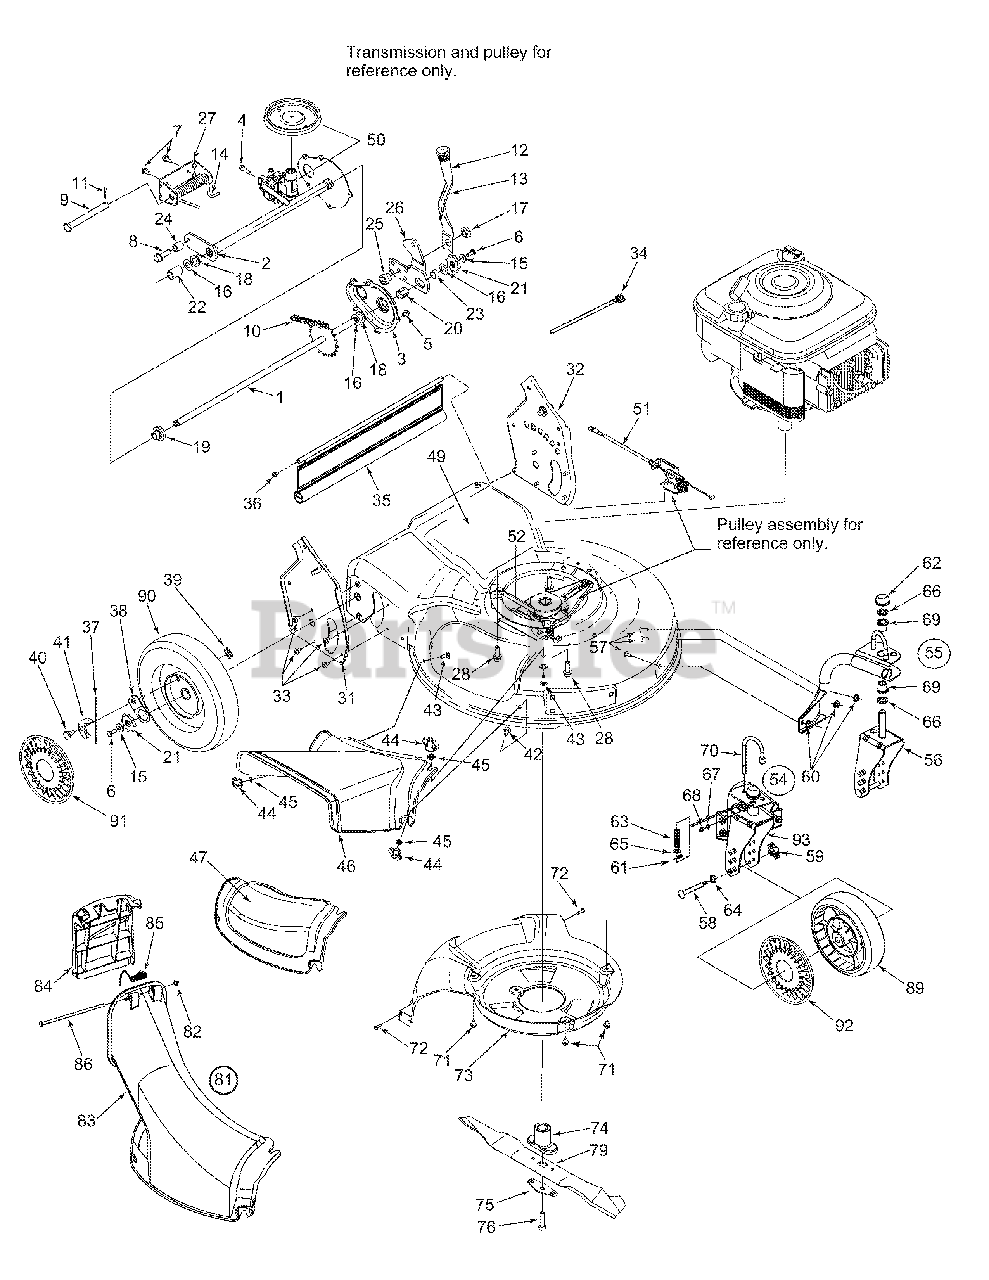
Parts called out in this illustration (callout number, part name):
1	Axle Ass’y 20T x 21.46" Lg.
2	Trans Axle Ass’y
3	Chain Cover Ass’y
4	Hex Wash HD Scr 5/16-18 x .62
5	Hex Wash HD Tapp Scr 1/4-20 x .38
6	Hex Bolt 1/4-20 x .62
7	Hex Wash Hd. Scr 1/4-20 x .625" Lg
8	TT Screw 3/8-16 x 1.25
9	Clevis Pin .5" Dia. x 4.62" Lg.
10	Chain, No. 48 End less .50 x 24 links
11	Cotter Pin
14	RH Torsion Spring
15	Cupped Wash. .25 ID x .88 OD x .062
16	Washer, Flat .505 ID x 1.0
17	Shoulder Nut .625 DIA. x .165
18	Flange Bear ing .506 ID
19	Hex Flange Bear ing
20	Hex Sleeve Bear ing .504 x .830 Lg.
21	Ratchet Wheel
22	Spacer .55 ID x .75
23	Sleeve .511 ID x .70 OD x .37" LG.
24	Spacer .38 x .625" Lg.
25	Shoulder Spacer .385 ID x .715" Lg.
27	Spring Bracket
28	Hex Wash HD Tap Scr 3/8-16 x .88
31	Handle Brkt. Ass’y RH
32	Handle Brkt. Ass’y LH
33	Screw AB 1/4-20
35	Rear Flap 17.25" Lg.
37	Spring Nylon
38	Pawl Plate
39	Toplock Flat Weldnut 1/4-20
40	Shoulder Screw .340 x .285: 1/4-20
42	Carriage Bolt 1/4-20 x .62
43	Carriage Bolt 1/4-10 x .75
44	Wing Nut
45	Bolt Retainer 1/4" x .50" OD
47	Mulching Baffle
49	Deck Ass’y 21" (w/logo)
50	Transmission Ass’y
51	SP Cable 51.0" Lg.
52	V-Belt 3/8 x 39.24" Lg.
54	RH Caster Ass’y
55	LH Caster Ass’y
56	Wheel Caster Brkt Ass’y LH
57	Carriage Bolt 5/16 x 18 x .62" Lg.
59	Wing Nut
60	Hex Flange L-Nut 5/16-18 Gr. F
61	Int. Cotter Pin 5/16 DIA
62	Push Cap 5/8" Dia Rod
63	Com pres sion Spring
64	Spring Washer .530 ID
65	Flat Washer .344 ID x .625 OD x .063
66	Flat Washer .63 ID x .12 OD x .12
67	Flat Washer .203 ID x .406 OD x .040
68	Grease Fit ting
69	Flange Bear ing .631 ID
71	Hex Wash HD Tapp Scr 1/4-20 x .38
72	Screw 1/4-15 X .75
73	Baffle
74	Blade Adapter (w/star)
75	Bell Blade Support
76	Hex Bolt 3/8-24 x 2.00 Gr. 8 Special
77	Wave Washer .51" ID
79	Blade 21" (w/star)
81	Chute Assembly
82	Push Cap .188 Rod
84	Chute Door
85	Torsion Spring
89	Front Wheel Ass’y 7 x 2 (Link/Blk/BB)
90	Rear Wheel Ass’y 9 x 2.125 (Drive/Zag/Blk)
91	Hub Cap -Grey
92	Hub Cap -Grey (Front, w/hole)
93	Wheel Caster Brkt. Ass’y RH
